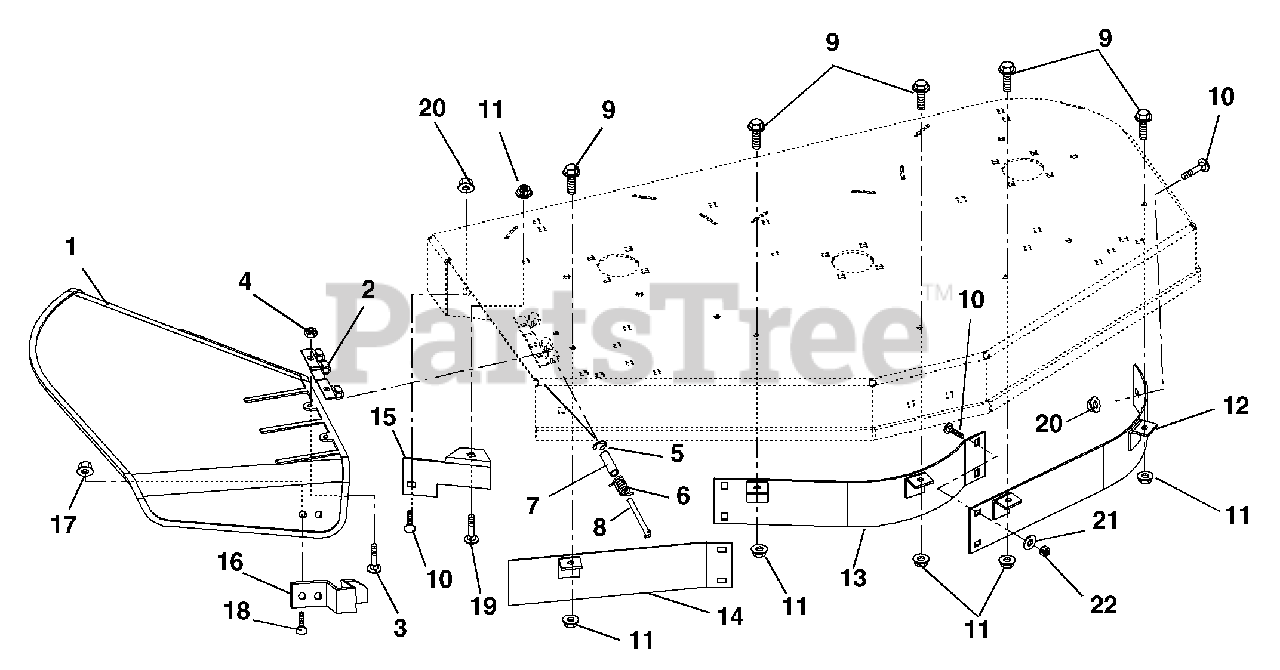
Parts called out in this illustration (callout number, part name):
1	DEFLECTOR, CHUTE
2	HINGE PLATE
3	@BLT-RDHDSQNK .25-20X.75 G5YZ
4	@NUT-SPNLK-FLG .25-20 YWZC
5	RG-RTNG-EXT .312X.025
6	SG-TORS .095X.50X 1.0
7	BSHG-SLV .334 X .502 X 1.437
9	BLT SERHFWH .31-18X.62 GR5BKZC
10	@BLT-RHDSSQNK .31-18X.62 G5YZ
11	@NUT-LK-NYL-FLG .31-18 YWZC
12	BAFFLE - LEFT FRONT - 40"
13	BAFFLE - CENTER FRONT - 40"
14	BAFFLE - RIGHT FRONT - 40"
15	DEFLECTOR-40"
16	FLAT SPRING
17	@NUT-LK-TOP-FLG .25-20 YWZC
18	@BLT-RDHDSQNK .25-20X.50 G5YZ
19	@BLT-RDHDSQNK .38-16X.75 G5YZ
20	@NUT-LK-NYL-FLG .31-18 YWZC
21	@WSHR-FL-STL.344X.688X.065YWZC
22	@NUT-LK-NYL .312-18 YWZC
